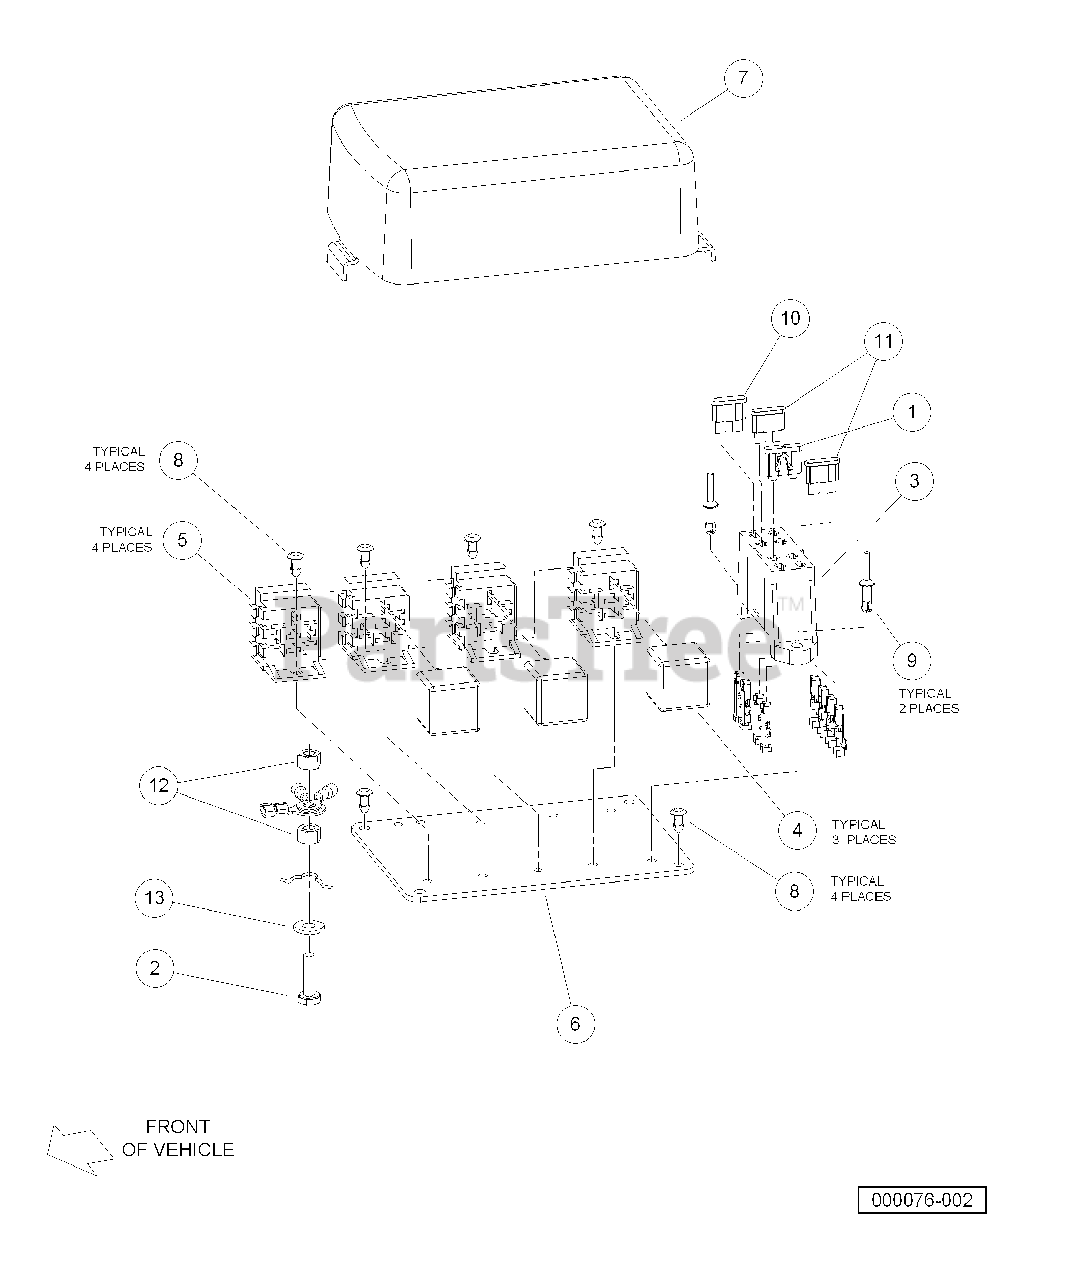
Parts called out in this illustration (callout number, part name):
1	Fuse, 10-Amp
2	Screw, 1/4-20 X .88 Hex Hd Cap
3	Fuse Block
4	Relay, Mini ISO, SPDT
5	Connector, Relay
6	Plate, Electrical
7	Cover, Electrical
8	Fastener, Push-in
9	Rivet, Drive
10	Fuse, 25-Amp
11	Fuse, 30-Amp
12	Locknut, 1/4-20 Dimpled
13	Washer, 1/4 Type A Narrow Flat
